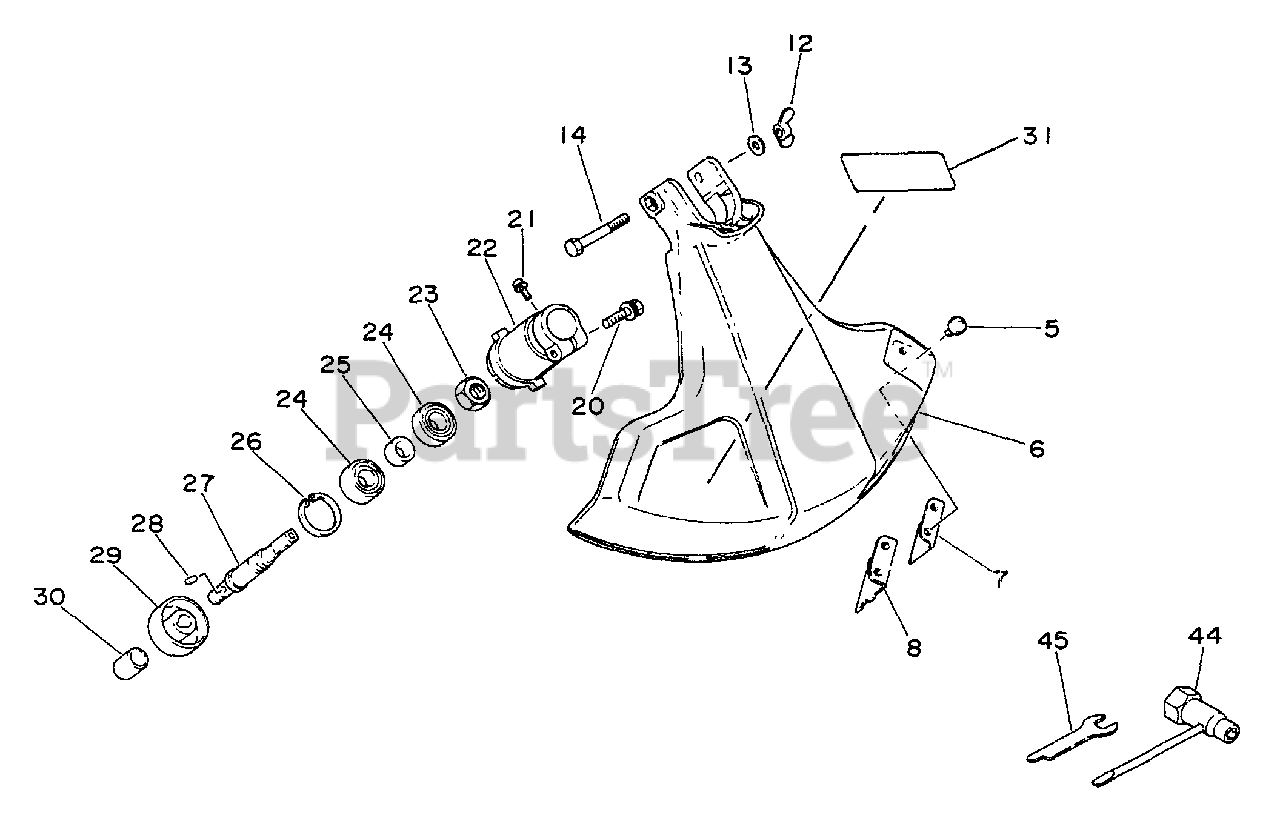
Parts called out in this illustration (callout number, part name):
5	SCREW 5×16
6	SHIELD
7	KNIFE, TRIMMER LINE
8	PROTECTOR
12	NUT, WING 6
13	WASHER 6.5×11.5×0.8
14	BOLT - 6×50
20	BOLT - 5×25
21	SCREW 4×10
22	CASE, GEAR
23	NUT 12 L.H.
24	BEARING, BALL 6001 DDU
26	RING, SNAP 28
27	SHAFT, GEAR
29	PLATE, ADAPTER - UPPER
31	LABEL, ECHO
44	WRENCH
